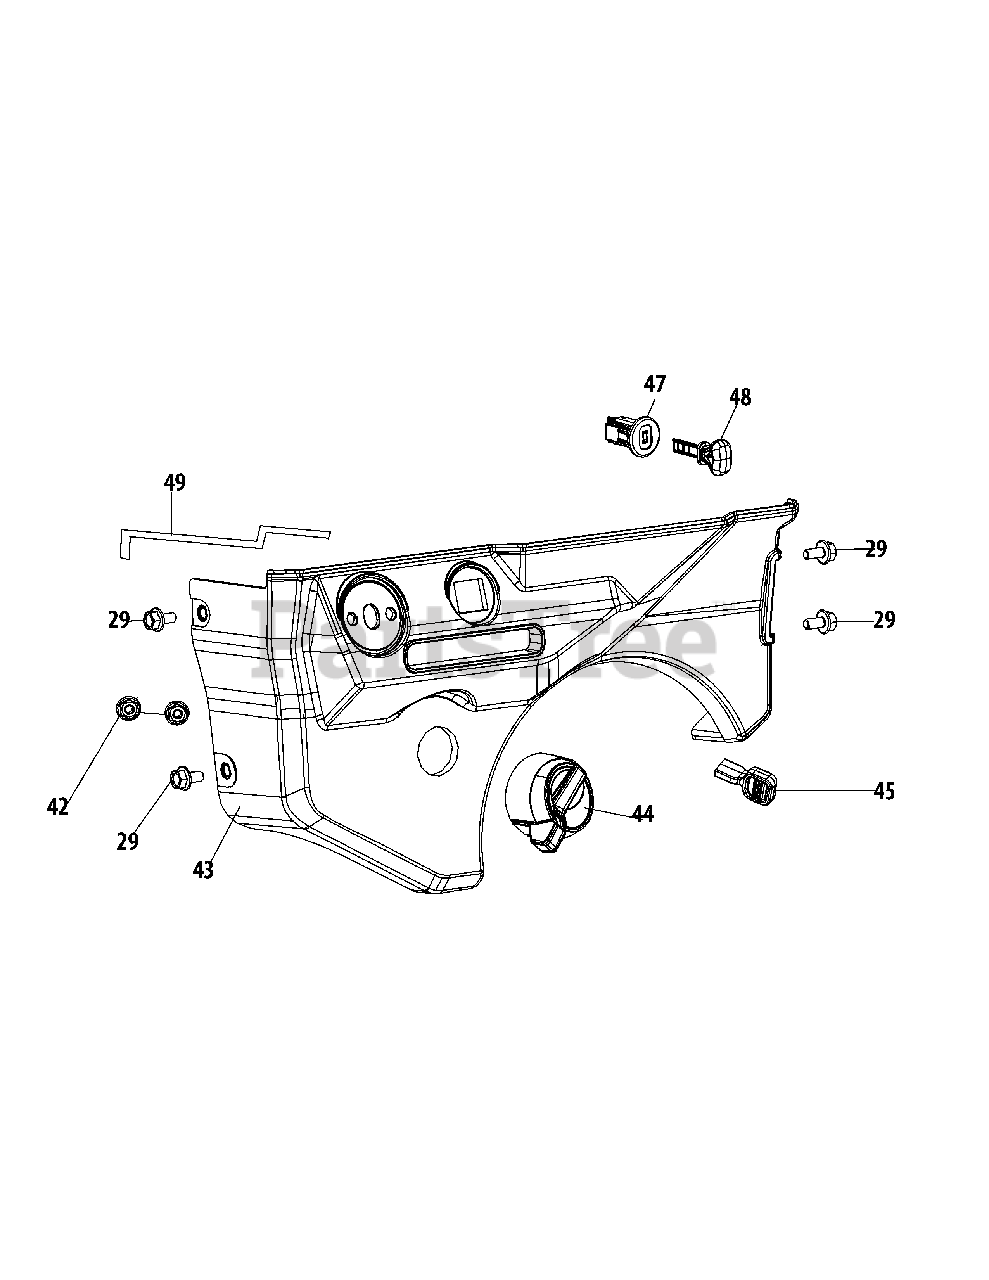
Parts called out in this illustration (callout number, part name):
29	Bolt M6×12
42	Flange Nut M6
43	Control Panel
44	Choke Lever
45	Throttle Lever Knob
47	Engine Switch Base
48	Engine Switch Key
49	Choke Linkage
